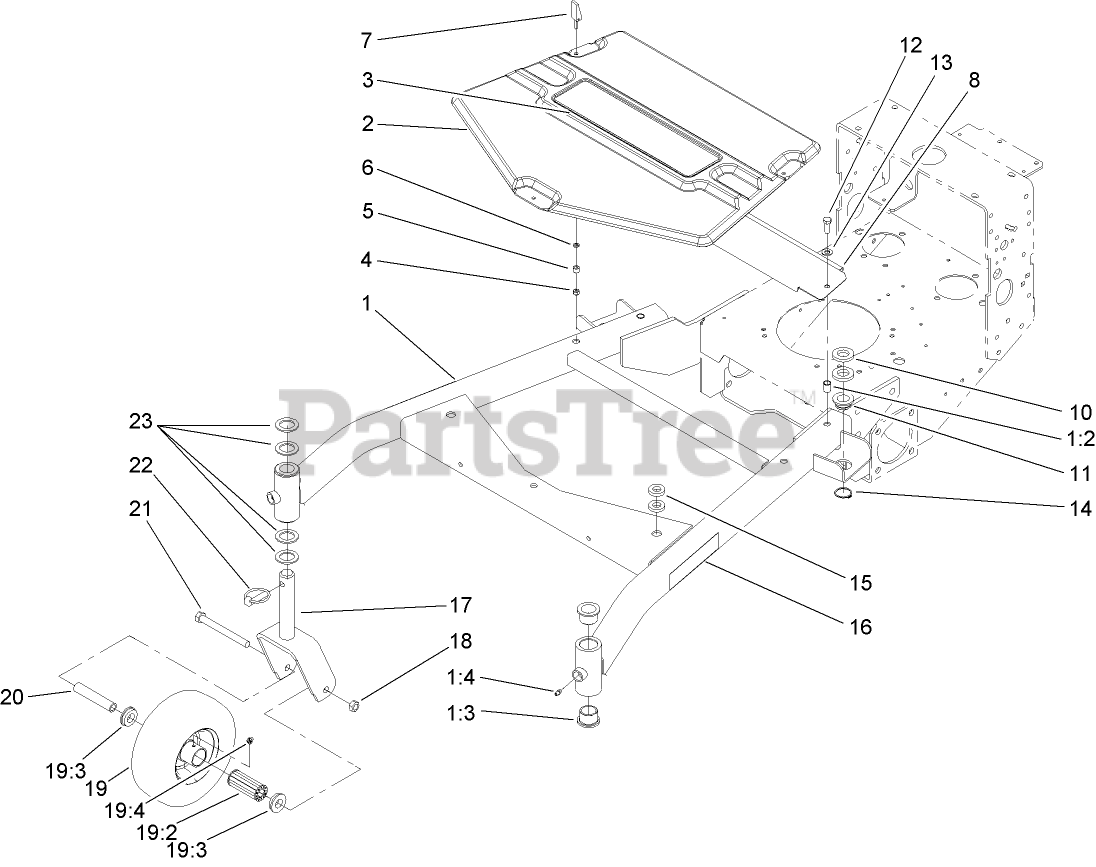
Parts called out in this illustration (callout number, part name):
1	CARRIER FRAME ASM
1:2	INSERT-NUT
1:3	BUSHING
1:4	FITTING-GREASE
2	COVER-FRAME, CARRIER
4	NUT-LOCK, HH
5	BUSHING-LATCH, SWELL
6	WASHER
7	HANDLE-LATCH, SWELL
8	SHIELD-BELT
10	SPACER-SUPPORT, DECK
11	BUSHING-DECK
12	SCREW-HH
13	WASHER-FLAT
14	RING-RETAINING
15	SPACER
16	DECAL-HOC
17	FORK-CASTOR
18	NUT-HEX
19	WHEEL AND TIRE ASM
19:2	BEARING-ROLLER
19:3	BUSHING
19:4	FITTING-GREASE
20	BUSHING-SPANNER
21	SCREW-HH
22	PIN-LYNCH
23	WASHER-THRUST
